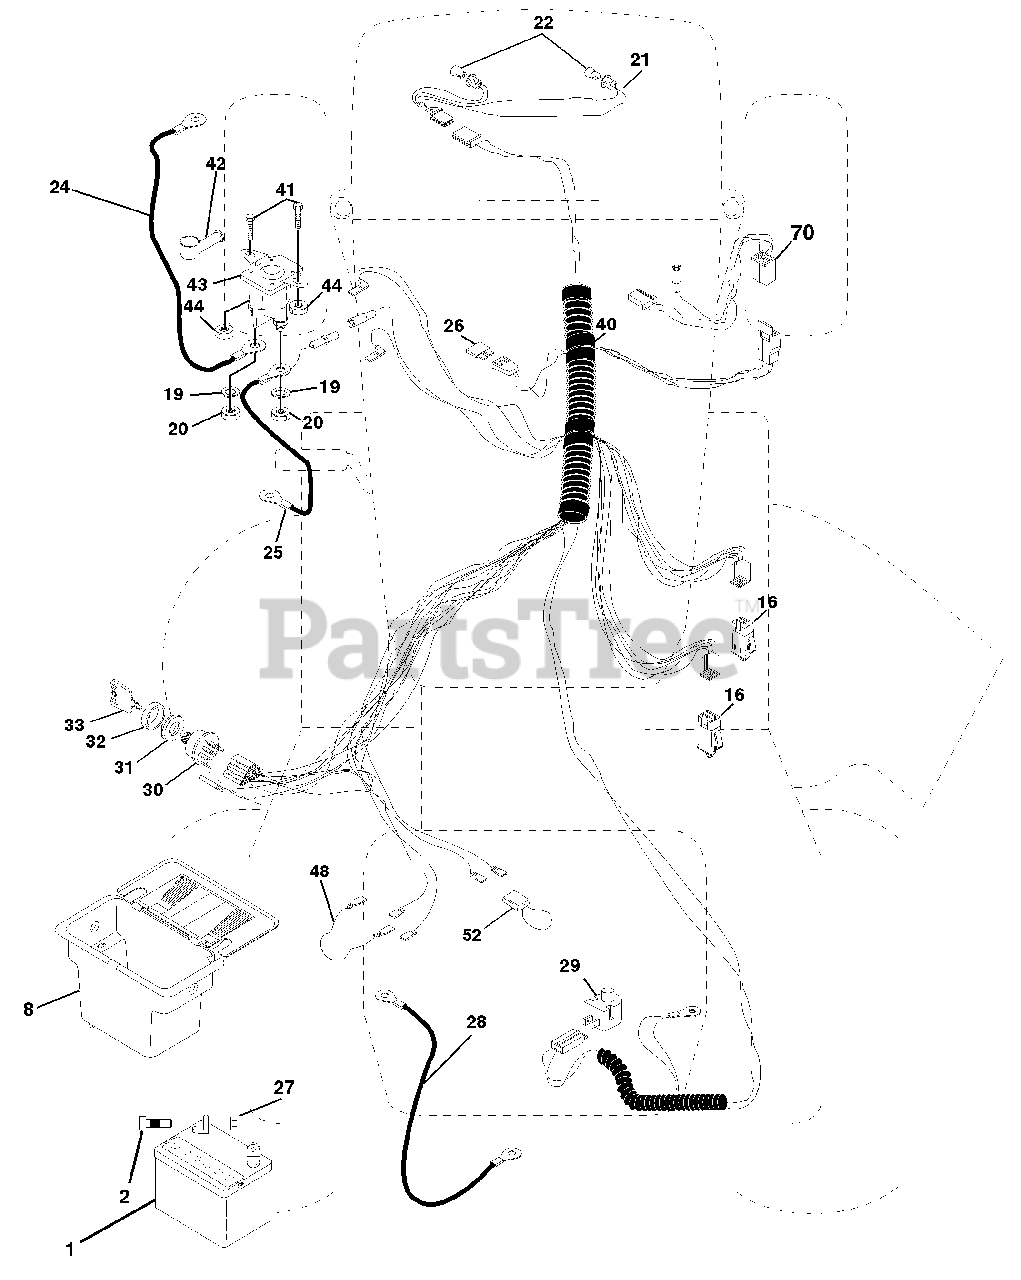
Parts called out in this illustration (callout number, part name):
1	Battery 12 Volt 25 AMP
2	Bolt Hex Hd 1/4-20unc X 3/4
8	Case Battery Mech Hinge
16	Switch Interlock Push-In
19	Washer Lock 1/4
20	Nut Jam Hex 1/4-20 Unc
21	Harness Asm Light W/4152j
22	Bulb Light #1156
24	Cable Battery 6 Ga 11" red
25	Cable Battery 6 Ga 44" red w/16 wire
26	Fuse 15 AMP
27	Nut Keps Hex 1/4-20 Unc
28	Cable Ground 6 Ga 12" black
29	Switch Plunger Nc Gray
30	Switch Ign 4 pos w/lights
31	Nut Ignition
32	Cover Sw Ignition
33	Key Ign Modelled Generic
40	Harness Ign.
41	Bolt Blk Fin Hex 1/4 - 20 x 1/2
42	Cover Terminal Red
43	Solenoid
44	Nut Keps Hex 1/4-20 Unc
48	Adapter Ammeter Rectangular
52	Protection Wire Loop
70	Harness, Eng.
